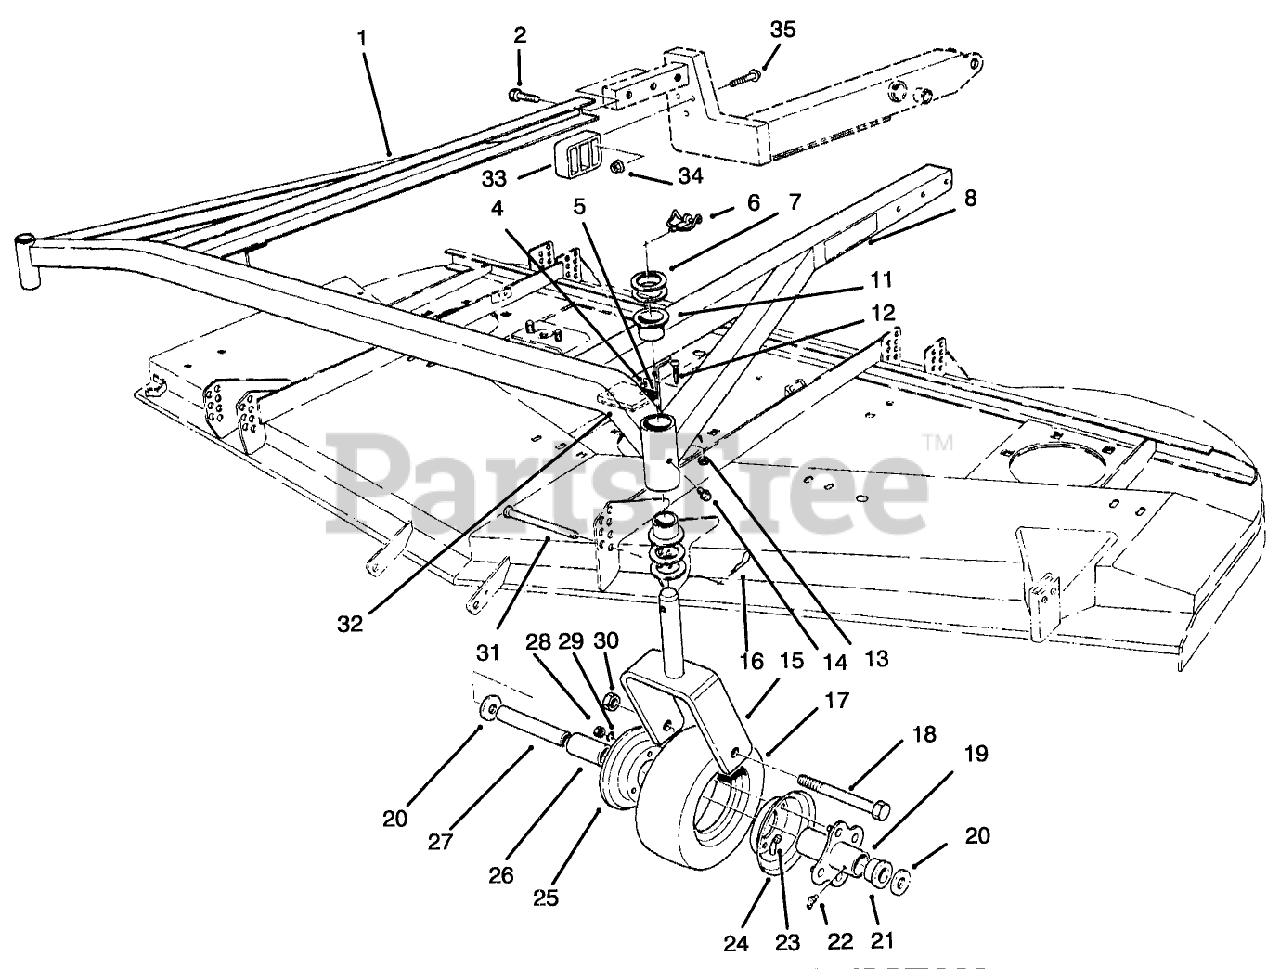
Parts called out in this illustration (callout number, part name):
1	CARRIER FRAME
2	SCREW-HH
4	SPACER
5	CUSHION-RUBBER
6	PIN-LYNCH
7	WASHER-THRUST
8	DECAL-HOC, LH
11	Bushing
13	NUT-LOCK, NI
14	FITTING-GREASE
15	Castor Fork
16	PIN-HAIR
18	SCREW-HH
19	HUB-CENTER
20	WASHER-FLAT
21	BEARING-OUTSIDE
22	FITTING-LUBE, 45 DEG
23	TUBE-INNER (W/VALVE)
24	FEMALE WHEEL HALF
25	MALE WHEEL HALF
26	BEARING-ROLLER
27	SPANNER-TIRE
28	NUT-HEX
29	WASHER-LOCK
30	NUT-HEX
31	PIN-CLEVIS
32	SHIM-CUSHION
33	Cradle-Rear
34	NUT-FLANGE
35	SCREW-HHF
